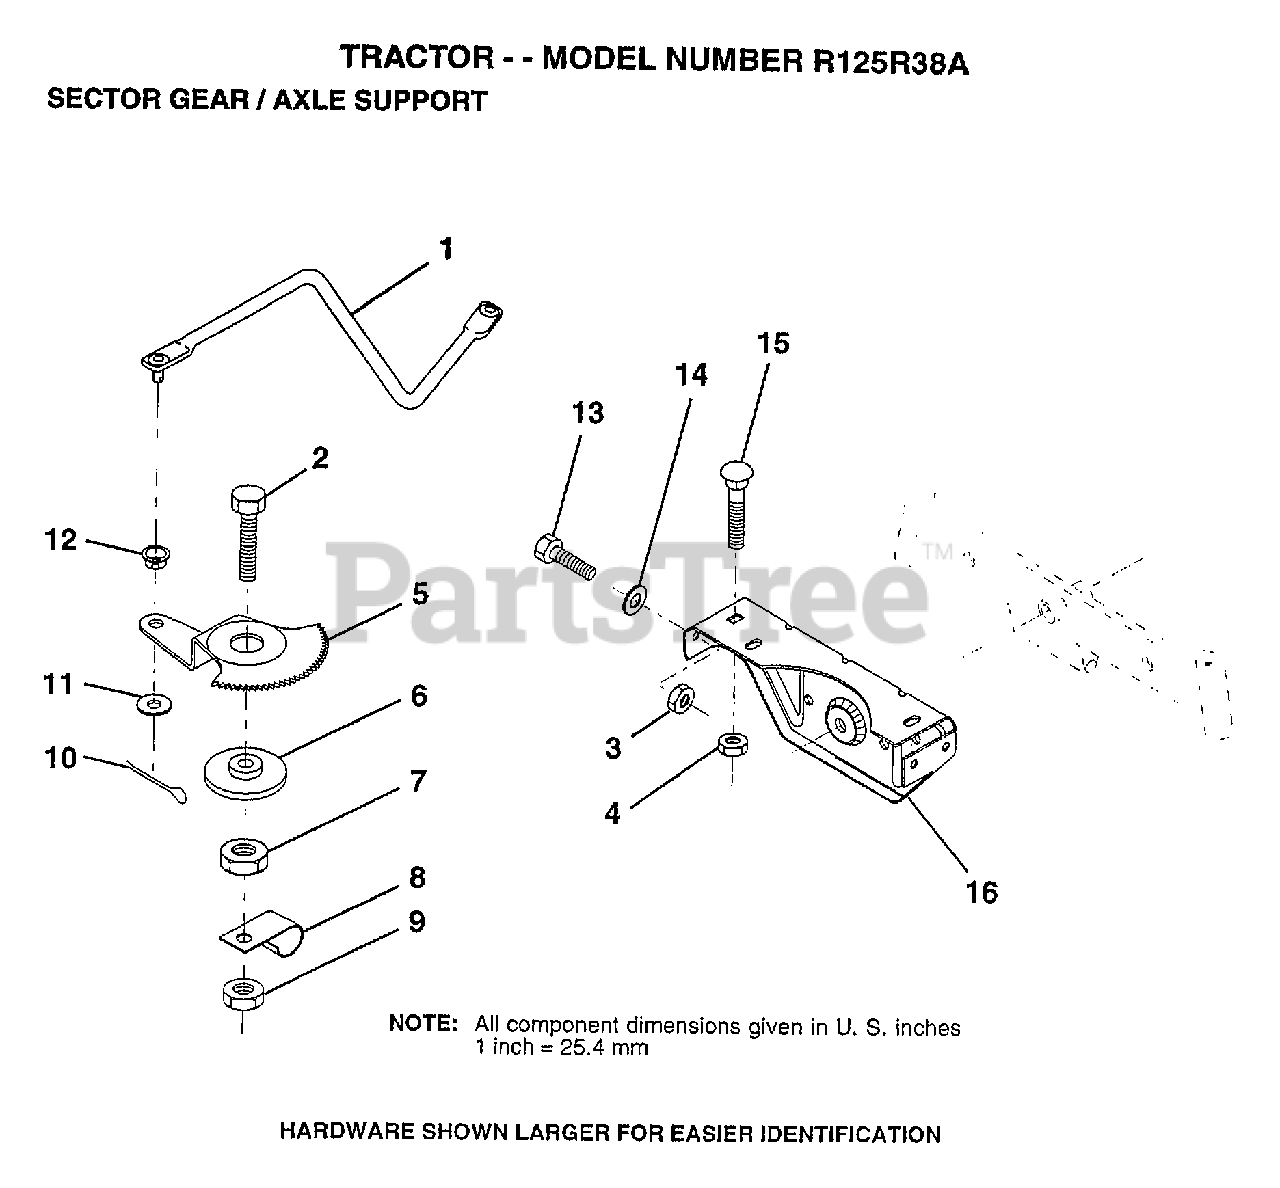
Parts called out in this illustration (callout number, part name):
1	DRAG LINK
2	"BOLT,HEX"
3	NUT
5	GEAR SECTOR
6	BUSHING
7	NUT
8	CLIP INSULATOR
9	NUT LTV
10	COTTER PIN
11	WASHER
12	BUSHING.DRAGLINK
13	BOLT
14	WASHER
15	BOLT
16	SUPT AXLE FRONT
